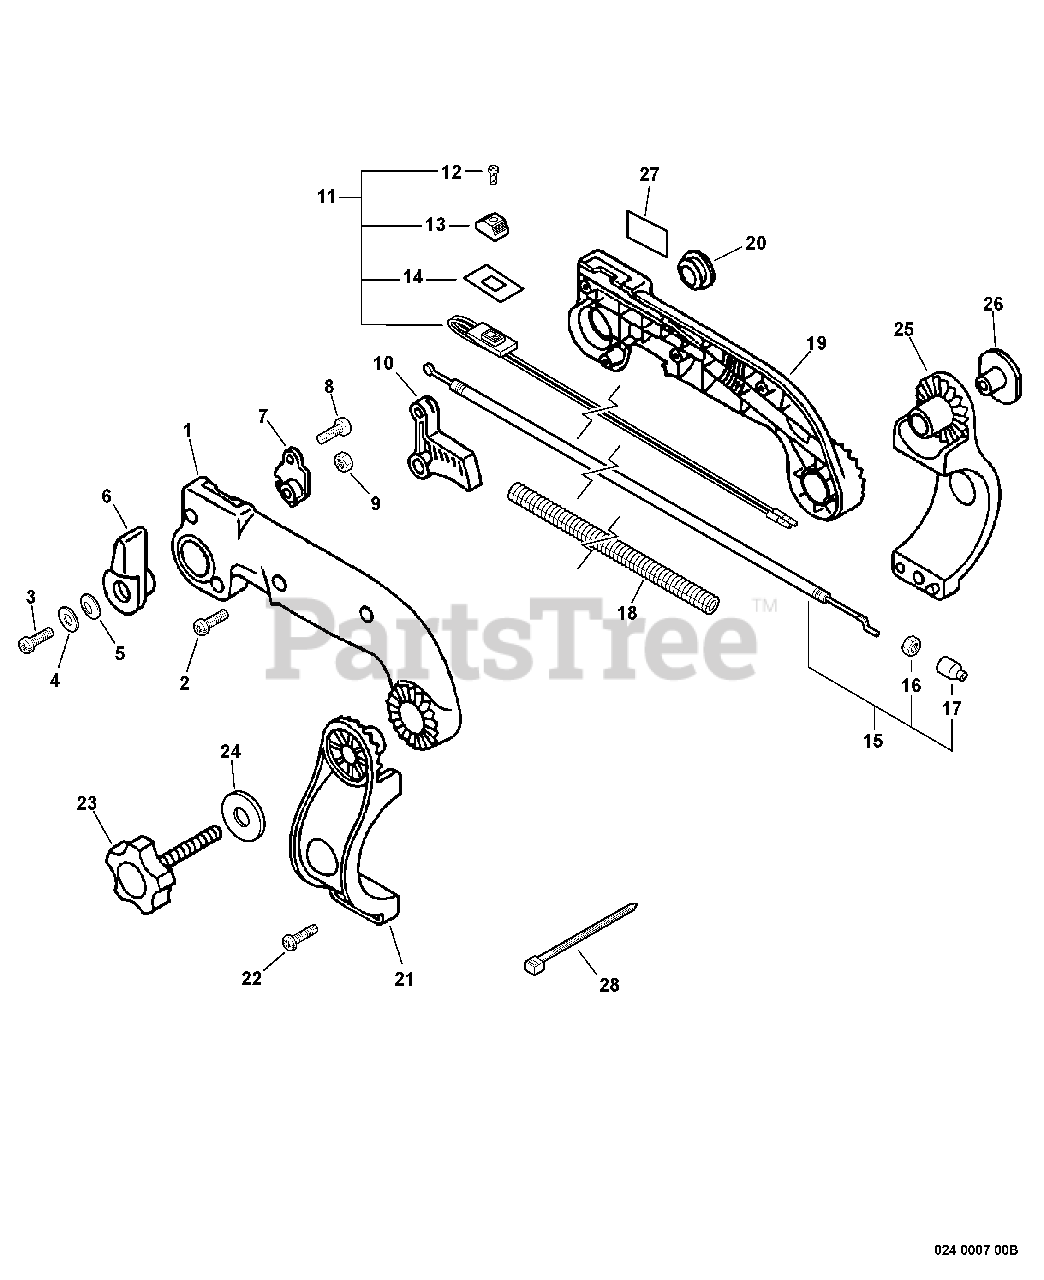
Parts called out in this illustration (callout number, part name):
1	CONTROL HANDLE - LEFT
2	SCREW 4×22
3	SCREW 6×20
4	WASHER, SPRING 6
5	WASHER 6.5×13×1
6	CONTROL, THROTTLE
7	BRACKET, THROTTLE
8	SCREW 4×10
9	NUT, HEX M6
10	TRIGGER, THROTTLE
11	SWITCH, ON-OFF
12	SCREW 3×10
13	KNOB, SWITCH - ORANGE
14	LABEL, SWITCH
15	CABLE, THROTTLE
16	NUT, HEX M6
17	CAP, DUST
18	TUBE, FLEXIBLE 7×790
19	CONTROL HANDLE - RIGHT
21	BRACKET, HANDLE - LEFT
22	SCREW, TAPPING 5×20
23	KNOB, SCREW
25	BRACKET, HANDLE - RIGHT
27	LABEL, ON-OFF
28	STRAP, TIE
